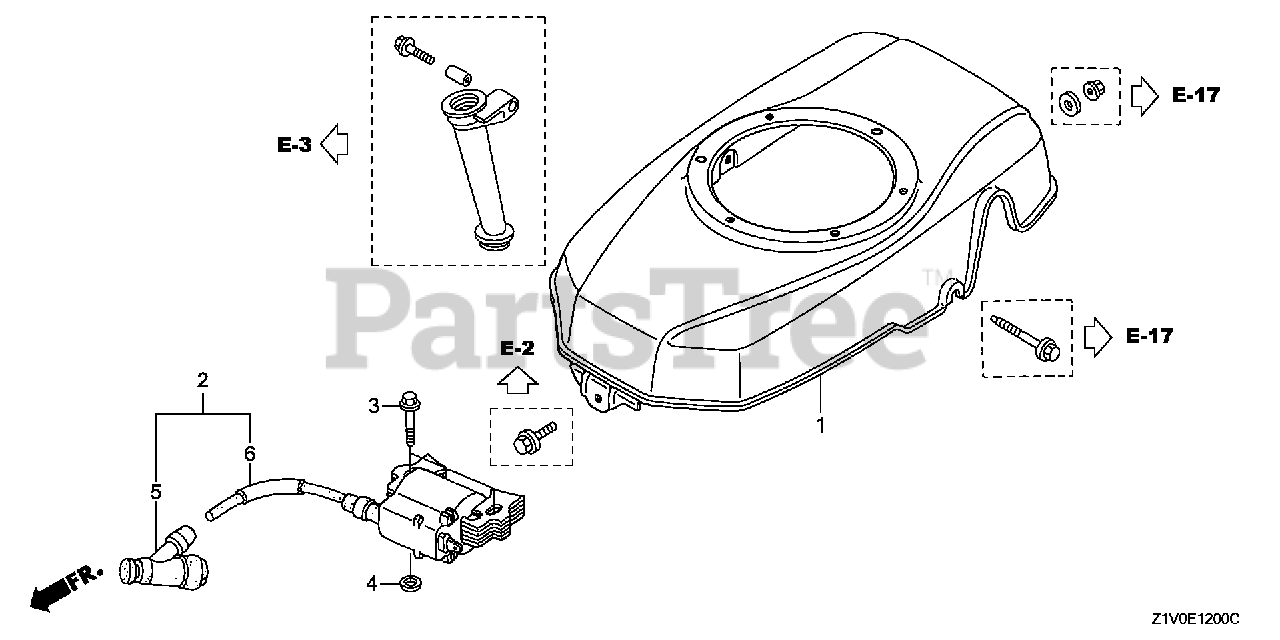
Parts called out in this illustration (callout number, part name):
1	COVER, FAN *NH1* (BLACK)
2	COIL ASSY., IGNITION
3	BOLT, FLANGE (6X28) (CT200)
4	WASHER, PLAIN (6MM)
5	CAP ASSY., NOISE SUPPRESSOR
